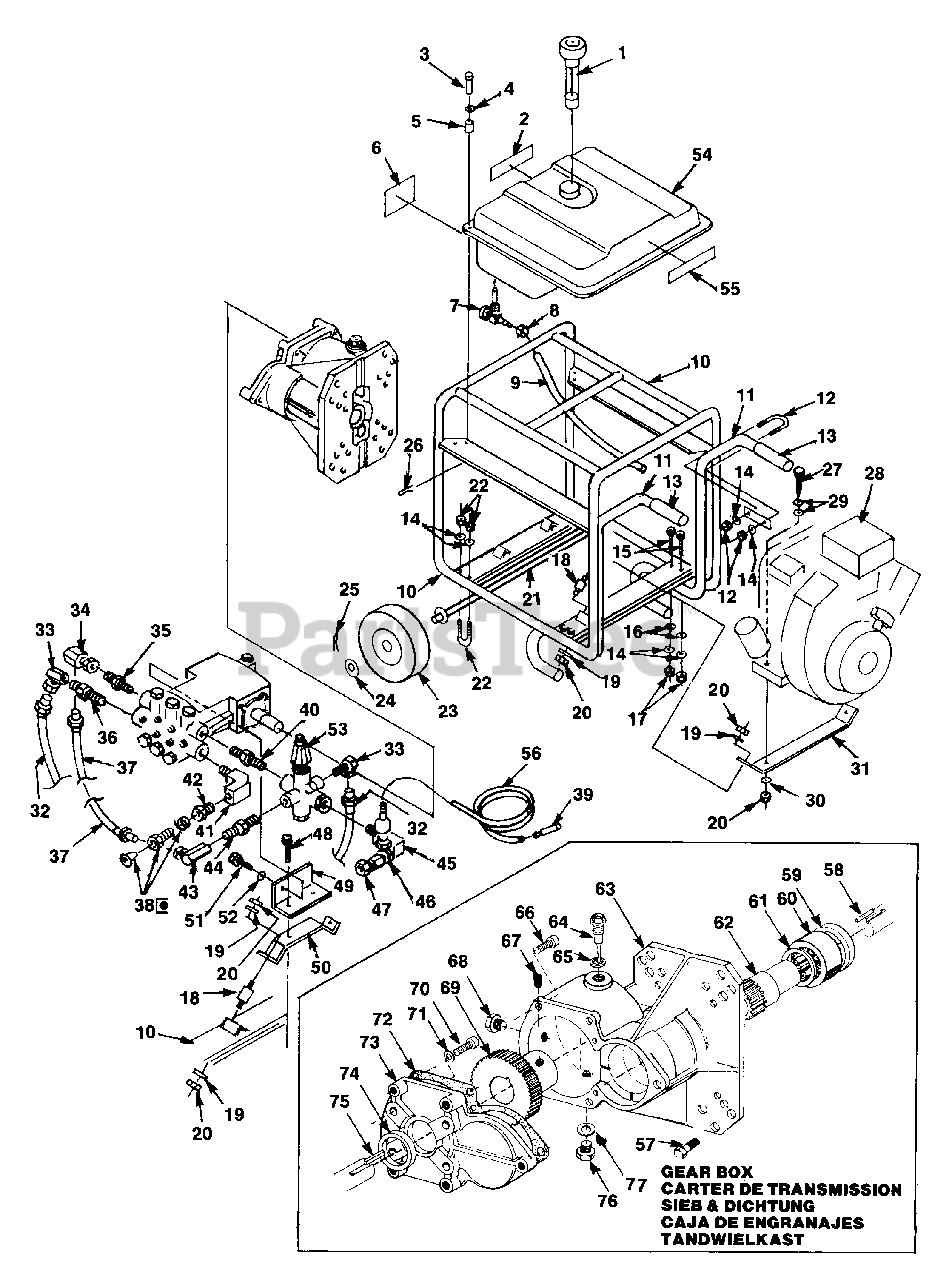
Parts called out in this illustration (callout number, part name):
2	OPER DECAL
3	PIN TBO
4	FLAT WASHER TBO
5	GROMMET-Isolator
6	DECAL, 172R24
7	VALVE- Fuel
8	Clip - Hose
9	HOSE-Fuel (8")
11	Tubing, Handle
13	GRIP- Handle
14	WASHER, LOCK
15	SCREW, CAP HEX HD
17	NUT-(1/4-20)
18	VIBRATION ISOLATOR
19	Washer - Lock (int.)
22	Superseded by UP05656
24	WASHER, FLAT (RDP3) TBO
25	COTTER PIN (RDP3) TBO
26	PIN TBO
27	SCREW - HEX CAP (5/16-18 x 1 1/2)
29	FLAT WASHER(HSD'S) TBO
30	3WASHER(HPW1200B) TBO
31	SUPPORT-Engine
32	BYPASS HOSE
33	SWIVEL ELBOW
36	BUSHING
38	SPRING & ADAPTOR
39	STRAINER
41	STREET ELBOW
45	3/8 NPT STREET ELBOW
48	BOLT- (5/16-18 x 3/4")
50	SUPPORT-Generator
51	Superseded by 80095
52	WASHER TBO TBO
54	FUEL TANK
70	SOCKET BOLT
